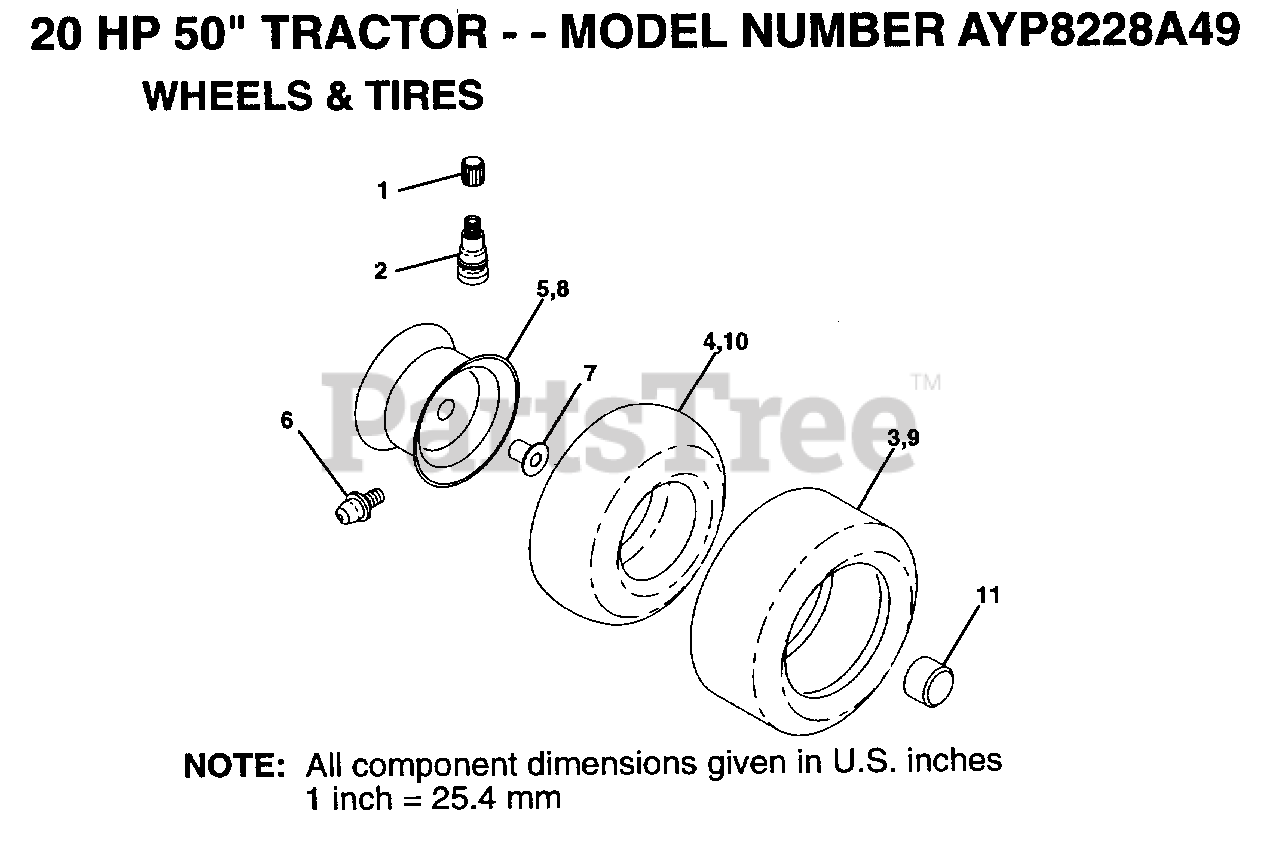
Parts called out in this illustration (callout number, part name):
1	VALVE CAP
2	VALVE STEM LT
4	TUBE.16X6.5/7.5-8
5	"RIM ASM 8"" FRT"
6	ZERK FITTING M
7	"FLANGE, BEARING"
8	"RIM ASM 12"" REAR"
10	TUBE.23X8/10-12
11	HUB CAP
